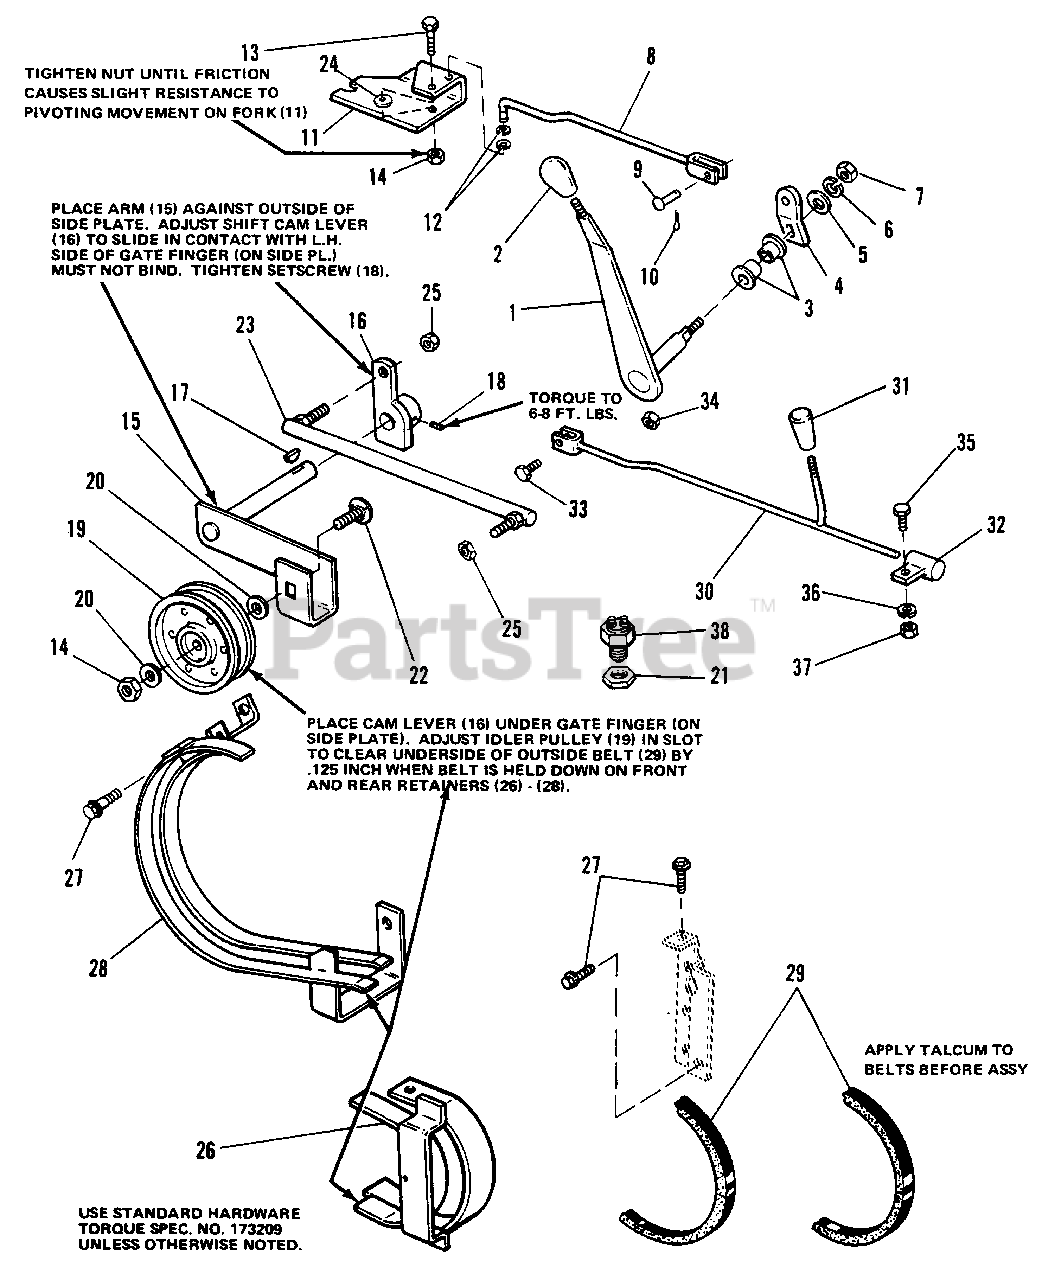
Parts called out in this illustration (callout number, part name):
1	CONTROL LEVER ASSEMBLY
2	KNOB
3	BUSHING, Flanged
5	WASHER, 3/8
6	LOCKWASHER, 3/8
7	NUT, Hex Full, 3/8-16
8	CONTROL ROD ASSEMBLY
10	PIN, Cotter, 3/32 x 3/4
11	FORK, Shift
13	CAPSCREW, Hex Hd., 3/8-16 x 2
14	LOCKNUT, Hex, 3/8-16
15	IDLER ARM ASSEMBLY
16	CAM SHIFT LEVER ASSEMBLY
17	KEY, Woodruff, No. 5 1/8 x 5/8
18	SETSCREW, Sq. Hd., 1/4-20 x 1/4
19	PULLEY (Idler)
20	WASHER, 5/16
21	NUT, Pal
22	BOLT, Carriage, 3/8-16 x 1-1/4
23	JOINT, Ball, Dbl. End
25	LOCKNUT, Hex, Full, 5/16-24
26	BELT RETAINER ASSY
27	SCREW, Taptite, 5/16-18 x 1/2
28	REAR RETAINER ASSY
29	BELT,"V", Drive
30	SHIFT ROD ASSY
31	HANDLE, Shift Rod
32	SHIFT ROD GUIDE ASSY
33	CAPSCREW, Hex Hd, 5/16-18 x 1-1/2
34	NUT, Hex, Full, 5/16-18
35	CAPSCREW, Hex Hd., 1/4-20 x 3/4
36	LOCKWASHER, 1/4
37	NUT, Hex, Full, 1/4-20
38	SWITCH, Interlock
